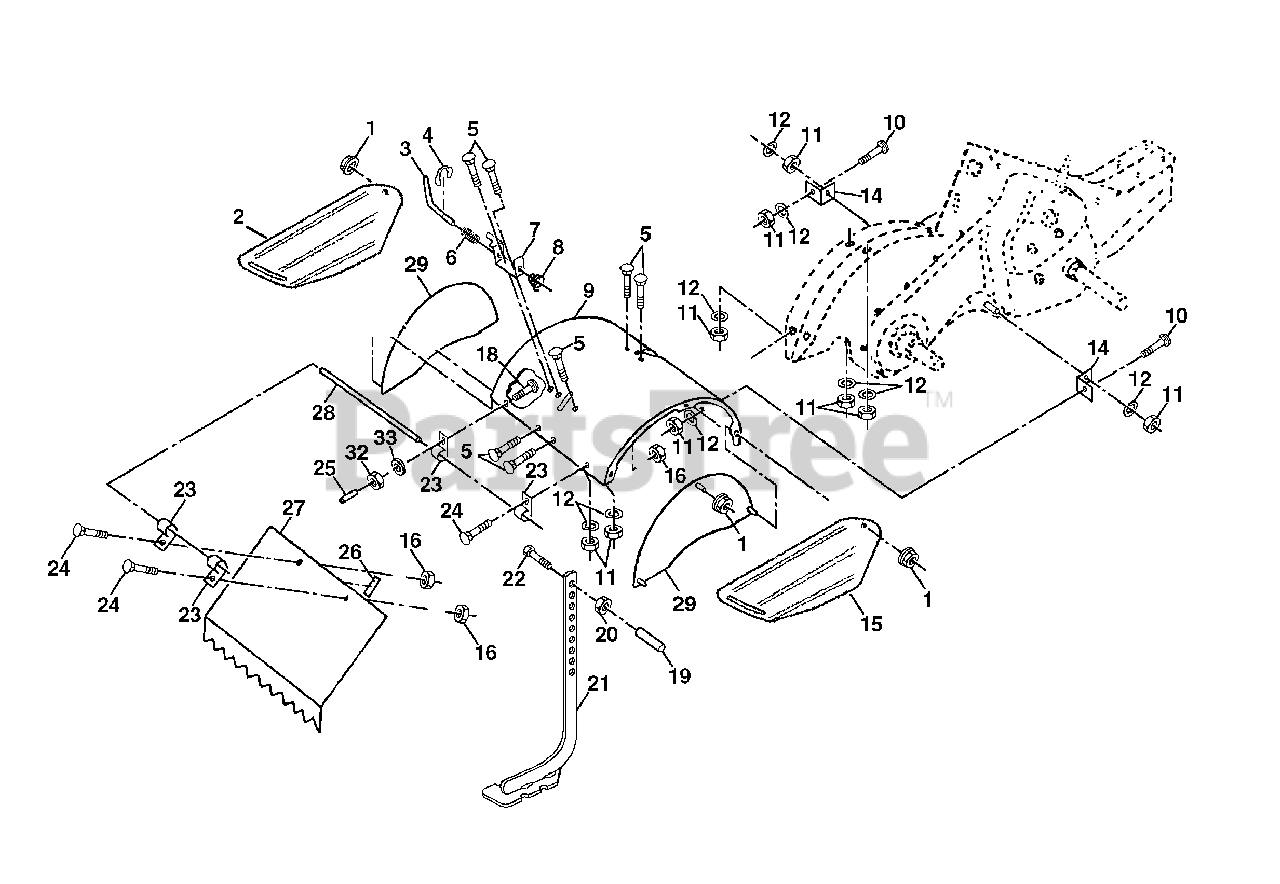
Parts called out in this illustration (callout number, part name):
1	Nut, Lock Hex Flange 5/16-18
2	Shield, Side, Outer, L.H.
3	Pin, Depth Stake
4	Ring, Klip
5	Bolt, Carriage 5/16-18 x 1
7	Bracket, Latch
8	Spring, Depth Stake
9	Shield, Tine
10	Bolt, Carriage 5/16-18 x 3/4 Gr. 5
11	Nut, Hex 5/16-18
12	Washer, Lock 5/16
14	Bracket, Shield Tine
15	Shield, Side, Outer R.H.
16	Nut, Hex, Flange 1/4-20 UNC
18	Bolt, Carriage 1/4-20 x 1-1/4 Gr. 5
20	Nut, Hex 3/8-16
21	Stake, Depth
22	Bolt, Hex 3/8-16 x 2
24	Bolt, RDHD SQNK 1/4-20 x 1/2
25	Cap, Vinyl
26	Pad, Idler
27	Shield, Leveling
28	Pin, Hinge
29	Shield, Side
32	Nut, Fin, Hex 1/4-20 UNC
33	Washer Lock 1/4
